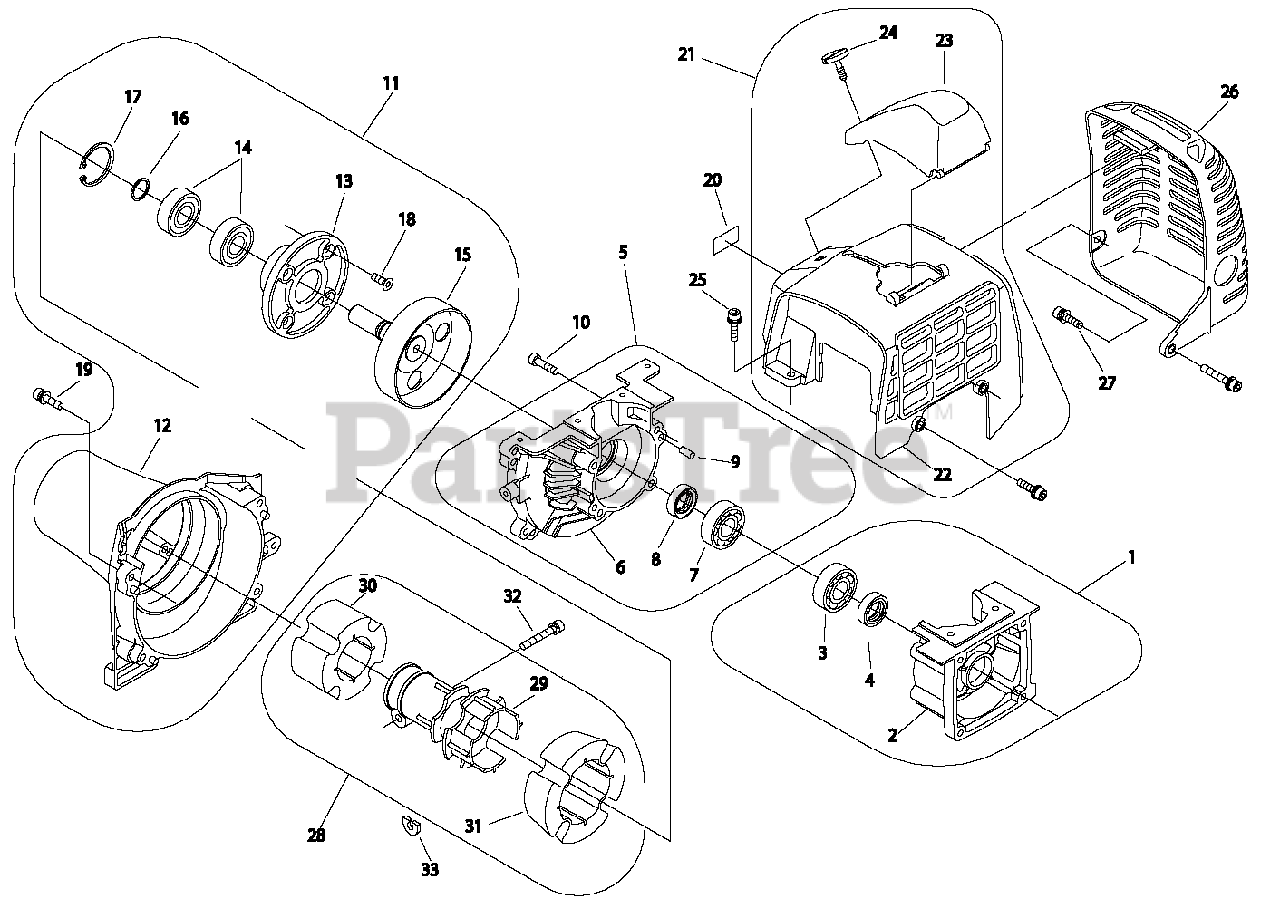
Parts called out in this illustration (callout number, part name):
1	CRANKCASE ASSY, S
2	CRANKCASE S
3	BEARING, BALL 6202
4	SEAL, OIL 16
5	CRANKCASE ASSY, M
6	CRANKCASE M
7	BEARING, BALL 6202
8	SEAL, OIL 16
9	PIN, LOCATING 5×10
10	BOLT 5×30
11	COVER ASSY, FAN
12	COVER, FAN
13	CASE, CLUTCH
14	BEARING, BALL 6202 DDU
15	DRUM, CLUTCH
16	RING, SNAP
17	RING, SNAP Ø35
18	SCREW M5×16
19	BOLT M5×30
20	LABEL, TRADE
21	COVER ASSY, ENGINE
22	COVER, ENGINE
23	COVER, SPARK PLUG
24	THUMBSCREW
25	BOLT M5×16
26	COVER, MUFFLER
27	BOLT M5×16
28	JOINT ASSY
29	JOINT
30	CUSHION, FRONT
31	CUSHION, REAR
32	BOLT M6×28
33	SHIM
